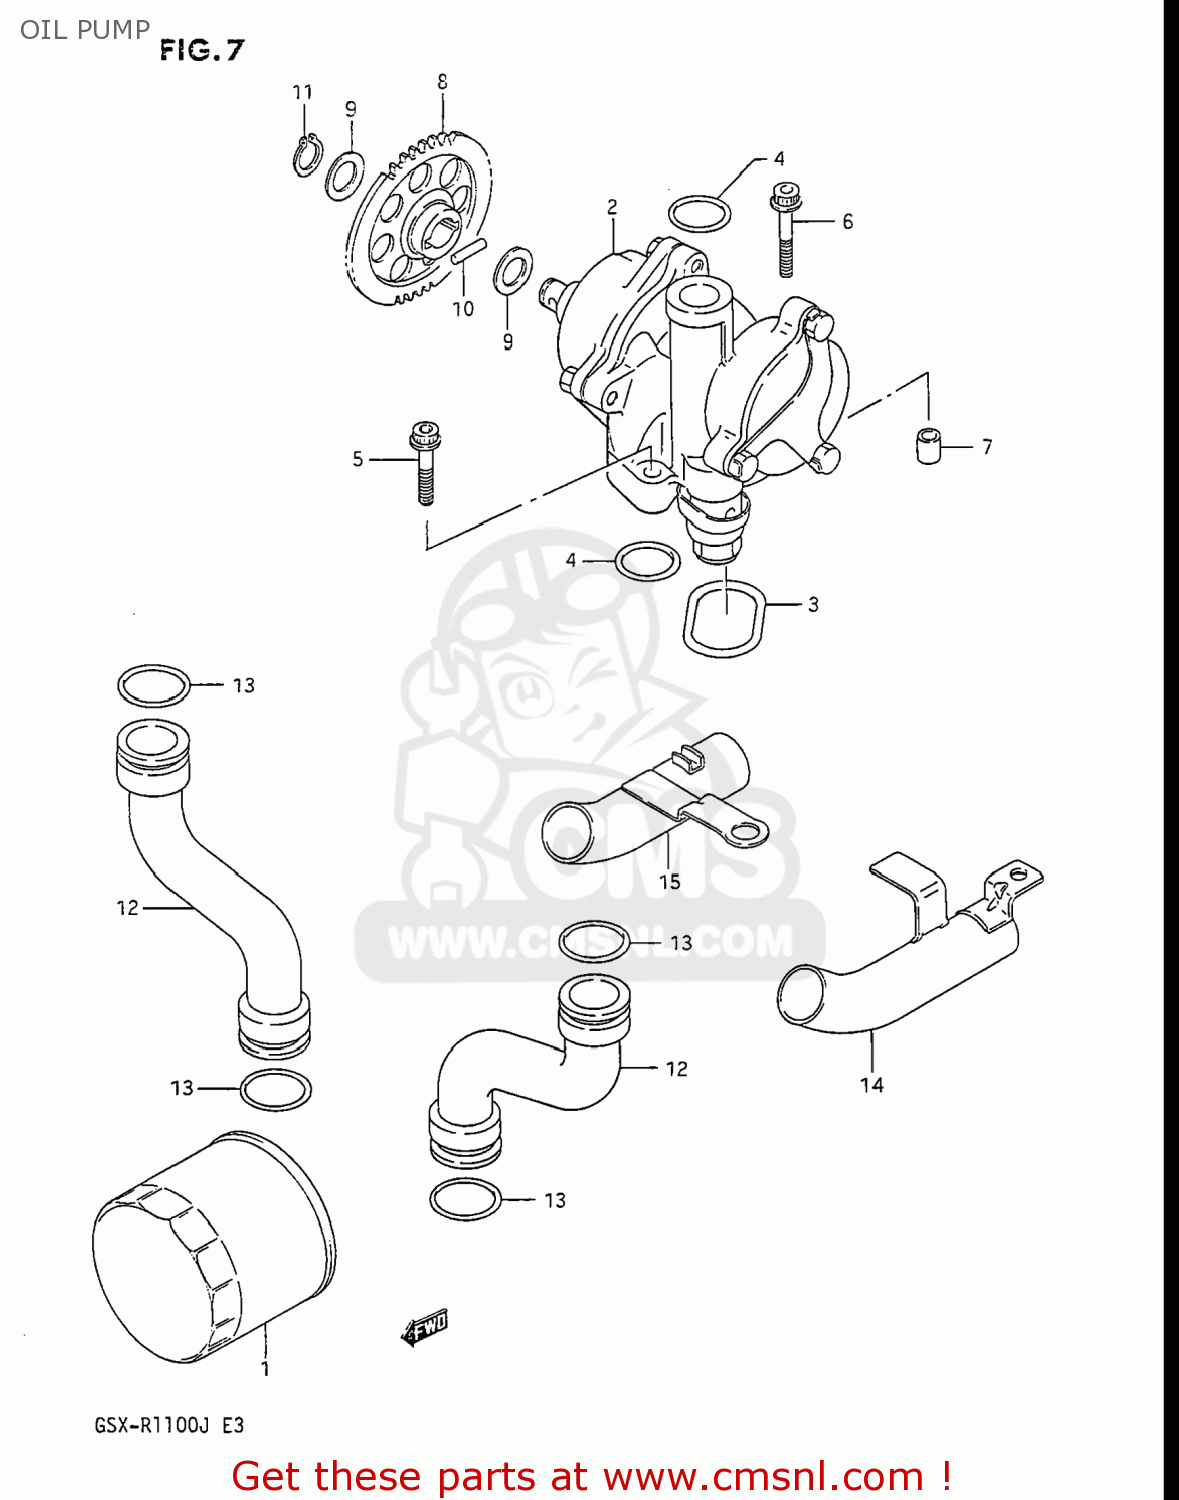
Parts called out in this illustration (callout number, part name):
1	FILTER,OIL
2	PUMP ASSY,OIL
3	O RING,OIL PUMP
4	O RING(D:3.2,ID:17.8)
5	BOLT
6	BOLT
7	PIN
8	GEAR,OIL PUMP DRIVEN
9	SHIM
10	PIN(5X18)
11	CIRCLIP
12	PIPE COMP,OIL OUTLET
13	O RING(D:3.7,ID:21.7)
14	PIPE,OIL,OUTLET,UNDER
15	PIPE,OIL,OUTLET,UNDER
